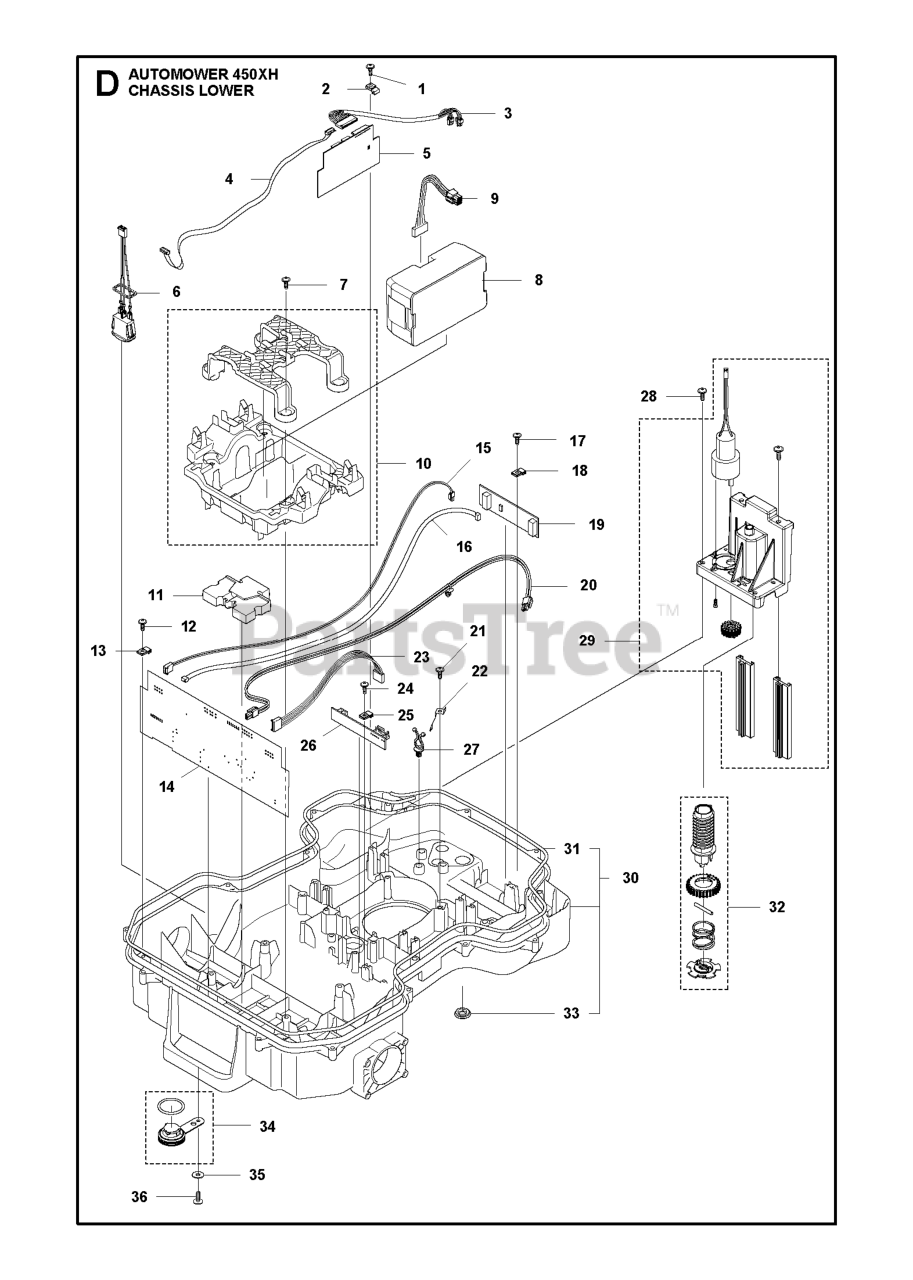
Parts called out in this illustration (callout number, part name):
1	SCREW 14MM
3	LOOM ULTRA SONIC EXTENSION
4	LOOM AUX
5	PRINTED CIRCUIT ASSY ULTRASONI
6	LOOM ON/ OFF
7	SCREW ITXPANT
9	WIRING ASSY BATTERY CABLE
10	HOLDER KIT BATTERY
11	WEIGHT 470G
12	SCREW 14MM
14	PRINTED CIRCUIT ASSY PCBA MAIN
15	WIRING ASSY LED LIGHT EXTENSIO
16	LOOM LOOP SENSOR
17	SCREW 14MM
19	PRINTED CIRCUIT ASSY LOOP SENS
20	LOOM CHARGING LINK HIGH CHARGI
21	SCREW 14MM
22	SPRING GUIDE HEIGHT ADJUSTMENT
23	LOOM HEIGHT ADJUSTMENT
24	SCREW 14MM
26	PRINTED CIRCUIT ASSY PCBA CUTT
27	HOLDER TWIST LOCK
28	SCREW 14MM
29	MOTOR ASSY HEIGHT MOTOR
30	CHASSIS KIT LOWER HI-CUT
31	SEALING STRIP
33	GROMMET M16
36	SCREW ITXPANT
